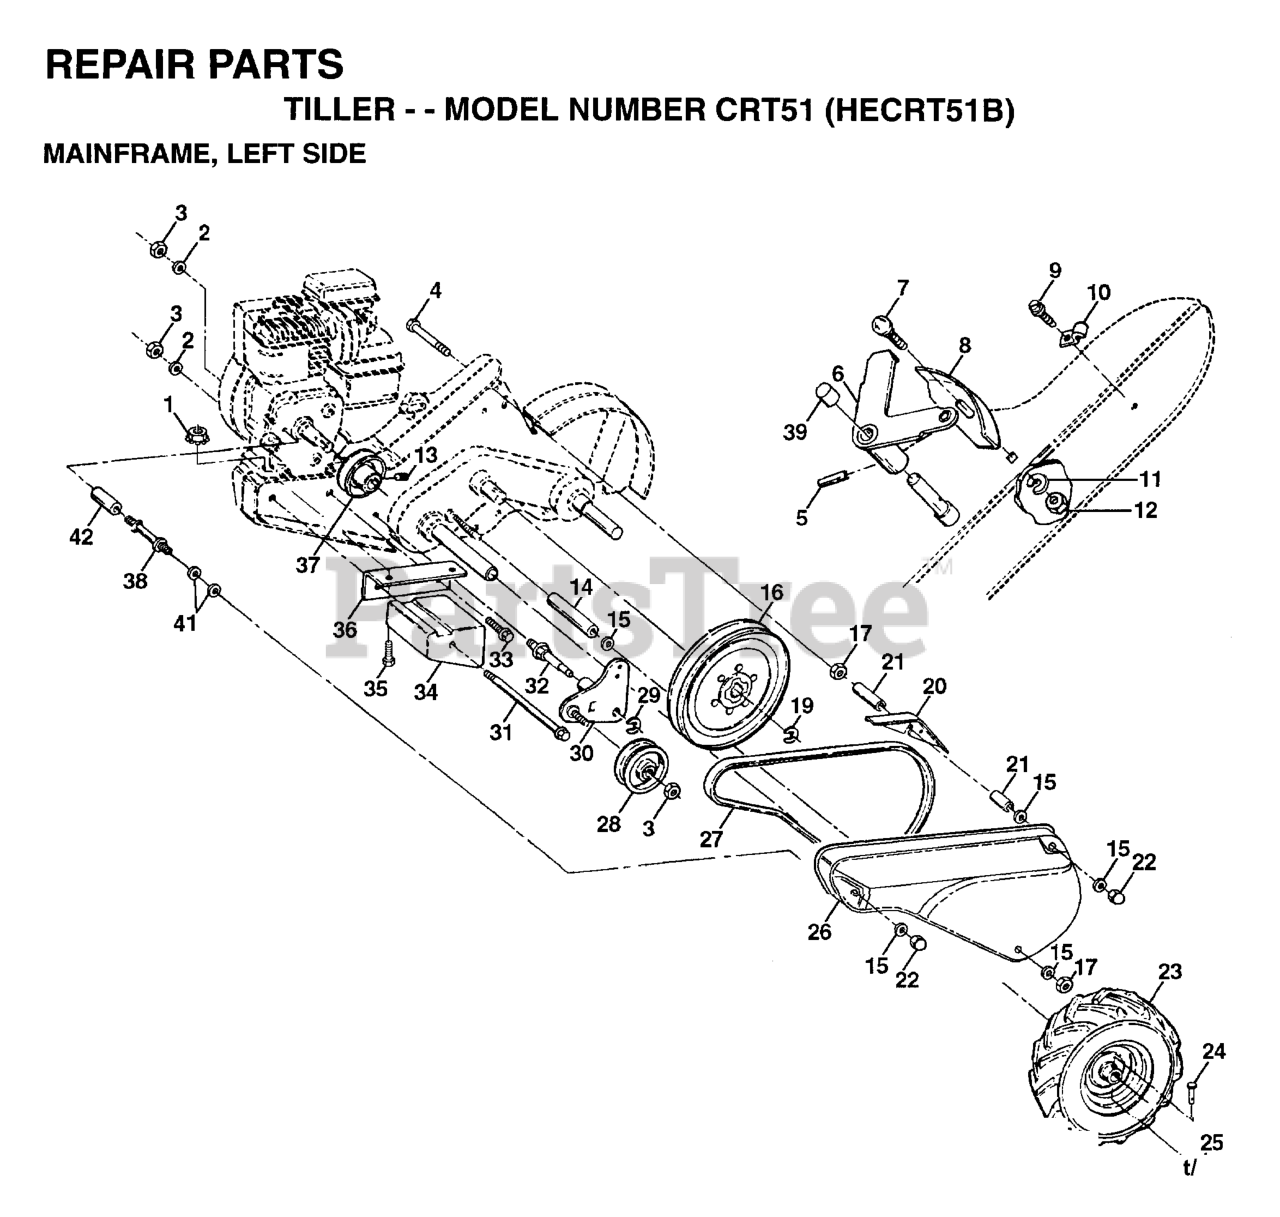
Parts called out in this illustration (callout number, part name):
1	NUT
2	WASHER, LOCK 3/8
3	NUT.HEX.3/8-16UNC
4	Bolt, Hex 5/16-18 x 4-1/4
5	DRIVE PIN
6	LEVER ASM CRT
8	PANEL.INDICATOR.SHIFT.BLACK
9	TAPPING SCREW
10	CONDUIT.CLIP.PLATED
11	LOCKWASHER
12	NUT
15	WASHER
16	SHEAVE, TRANSMISSION
19	RETAINING RING LT
21	SPACER, SPLIT
23	TIRE.16X4-8.CHEVRON.TILLER
24	RIVET,DRILLED
25	RETAINER M
26	BELT GUARD
27	V-BELT
28	PULLEY-IDLER TI
30	BRACKET ASSY TI
31	BOLT.FIN.HEX.3/8-16UNC
32	SHIFT ARM CRT
33	BOLT
34	COUNTERWEIGHT.LH.CRT
35	Bolt Fin Hex 5/16 - 18 Unc x 2 Gr. 2
36	BRACKET LH CRT
37	RP.ENGINE PULLEY
38	BELT GUARD STUD
39	CAP.PLUNGER.BLACK
